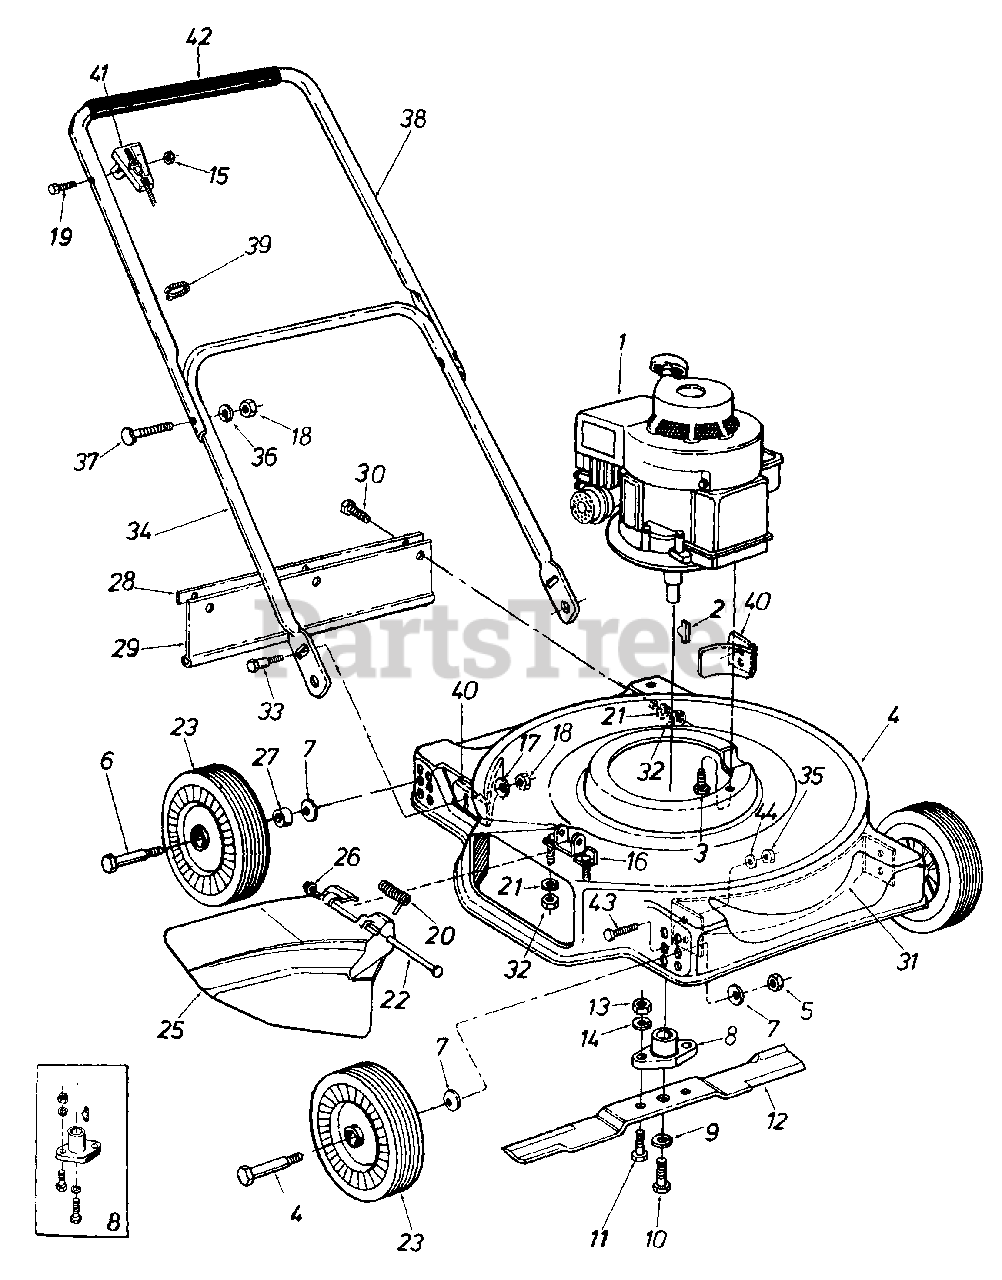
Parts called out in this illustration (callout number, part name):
1	Engine
2	#6 Hi-Pro Key 5/32 x 5/8" Dia.
3	Hex Wash. Hd. Tap Scr. 3/8-16 x .88" Lg.
4	20" Deck
5	Hex Nut 3/8-16 Thd.
6	Axle Bolt - Rear
7	Belleville Wash. 3/8" I.D.
8	Blade Adapter Kit
9	L-Wash. 3/8" I.D. Heavy Duty
10	Hex Bolt 3/8-24 x 1.50" Lg. (Grade 5)
11	Hex Bolt 5/16-24 x 1.00" Lg. (Grade 5)
12	20" Blade
13	Hex Nut 5/16-24 Thd.
14	L-Wash. 5/16" I.D.
15	Hex Cent. L-Nut 1/4-20 Thd.
16	Deflector Hinge Plate
17	Belleville Wash.
18	Hex Nut 5/16-18 Thd.
19	Hex Bolt 1/4-20 x 1.50" Lg.
20	Torsion Spring
21	L-Wash. 1/4" I.D.
22	Hinge Pin 3/16" Dia. x 3.88" Lg.
23	Wheel Ass'y. Comp. 7 x 1.50
24	Axle Bolt - Front
25	Chute Deflector
26	Push Nut .19 Rod
27	Spacer .511" I.D. x .70" O.D. x .38" Lg.
28	Retaining Strip
29	Flap Ass'y.
30	Hex Bolt 1/4-20 x .62" Lg.
31	Front Baffle (20")
32	Hex Nut 1/4-20 Thd.
33	Shoulder Bolt .437" Dia. x .268" Lg.
34	Lower Handle
35	Hex Nut 3/8-16 Thd.
36	L-Wash. 5/16" I.D.
37	Curved Hd. Carriage Bolt 5/16-18 x 1.38" Lg.
38	Upper Handle
39	Plastic Cable Tie
40	Rear Baffle
41	Throttle Control Ass'y. Comp.
42	Grip - Blue
43	Hex Bolt 3/8-16 x .62" Lg.
44	Belleville Washer
